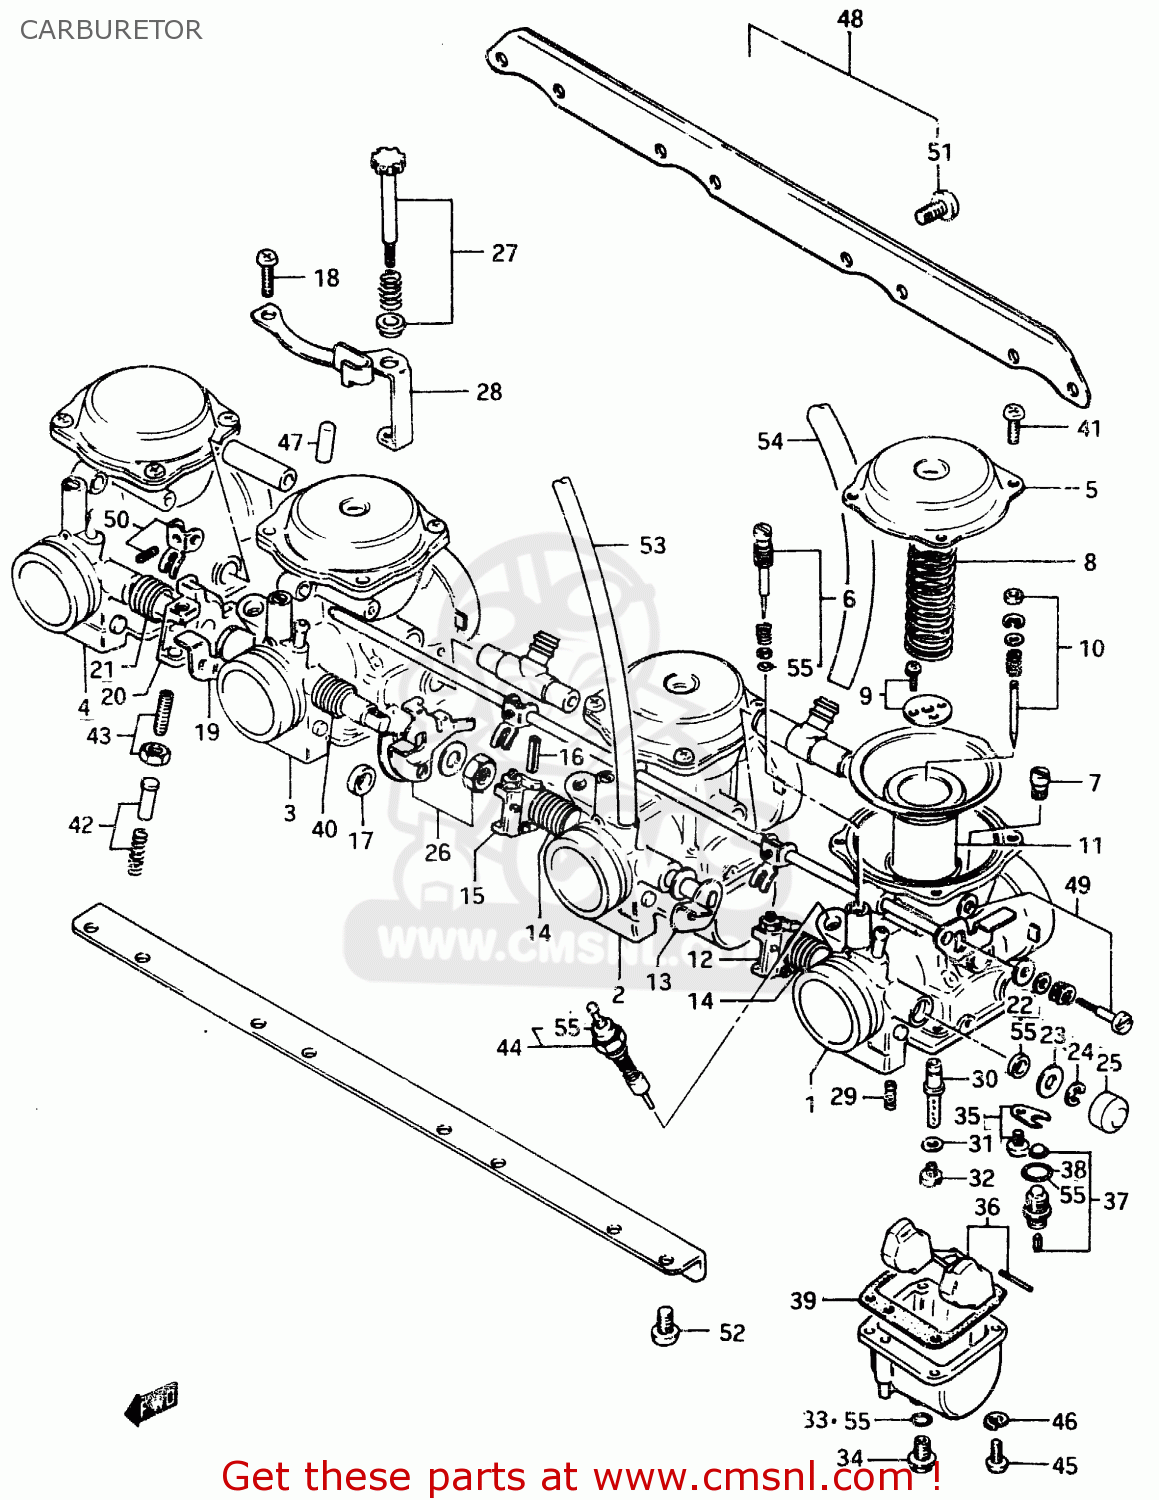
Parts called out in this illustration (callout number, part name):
1	CARBURETOR, NO. 1
2	CARBURETOR, NO. 2
3	CARBURETOR, NO. 3
4	CARBURETOR, NO. 4
5	COVER
6	ADJUSTER SET
7	JET,MAIN(165)
8	SPRING
9	PLATE SET
10	JET NEEDLE SET (4CFX16-3)
11	DIAPHRAGM ASSEMBLY
12	SHAFT, THROTTLE
13	SHAFT, THROTTLE
14	SPRING
15	LEVER, THROTTLE
16	PIN,THROTTLE SHAFT
17	SPACER,THROTTLE SHAFT
18	SCREW
19	SHAFT, THROTTLE
20	SHAFT, THROTTLE
21	SPRING
22	SEAL
23	GASKET,THROTTLE SHAFT (NAS)
24	E RING
25	CAP
26	THROTTLE LEVER SET
27	IDLE ADJUSTER SET
28	BRACKET, IDLE ADJUSTER
29	JET, PILOT (37.5)
30	JET, NEEDLE (0-8)
31	WASHER,NEEDLE NOZZLE
32	JET,MAIN(97.5)
33	GASKET (NAS)
34	PLUG,DRAIN
35	PLATE
36	FLOAT SET
37	VALVE ASSY,NEEDLE
38	O-RING,NEEDLE VALVE
39	GASKET,FLOAT CHAMBER (NAS)
40	SPRING,THROTTLE SHAFT
41	SCREW
42	SPRING SET
43	SCREW SET
44	STARTER PLUNGER SET
45	SCREW
46	LOCK WASHER
47	CAP
48	FLANGE SET
49	SCREW SET
50	STARTER LEVER SET
51	SCREW
52	SCREW 6X12
53	HOSE
54	HOSE
55	GASKET SET (NAS)
